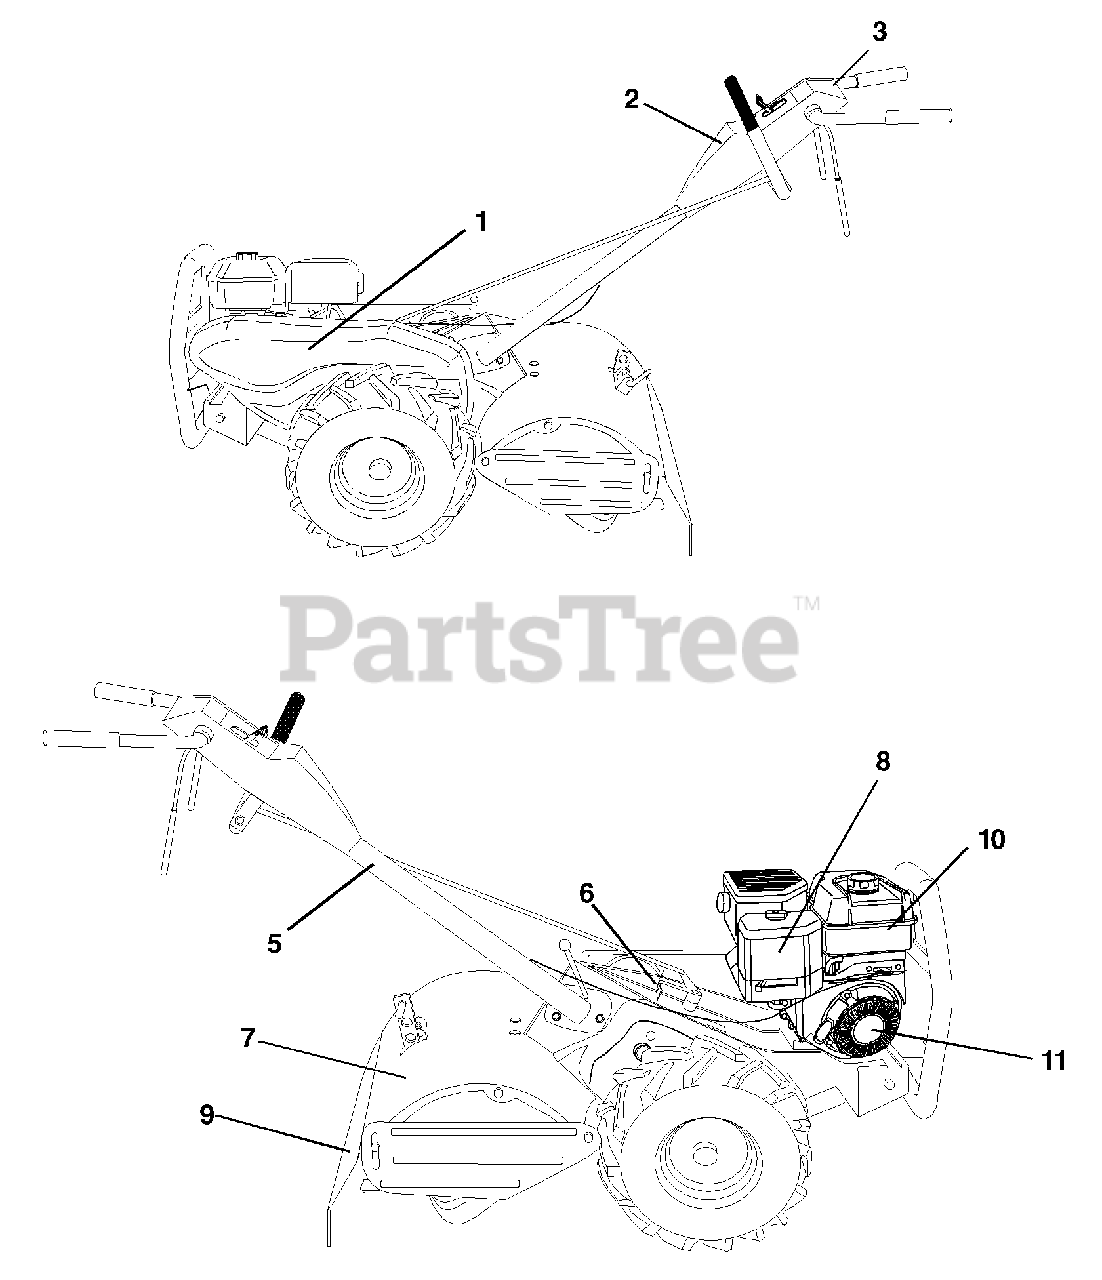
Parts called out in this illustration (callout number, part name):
1	Decal, Blt Grd
2	Decal, CNTRL PNL
3	Decal, Logo
5	Decal, Hand Placement
6	Decal, Shift Indicator
7	Decal, Warning
8	Decal, Engine B&S 6.5 HP
9	Decal, Warning, Rotating Tines
10	Decal, Engine Intek REF
11	Decal, Rewind Intek #274350
